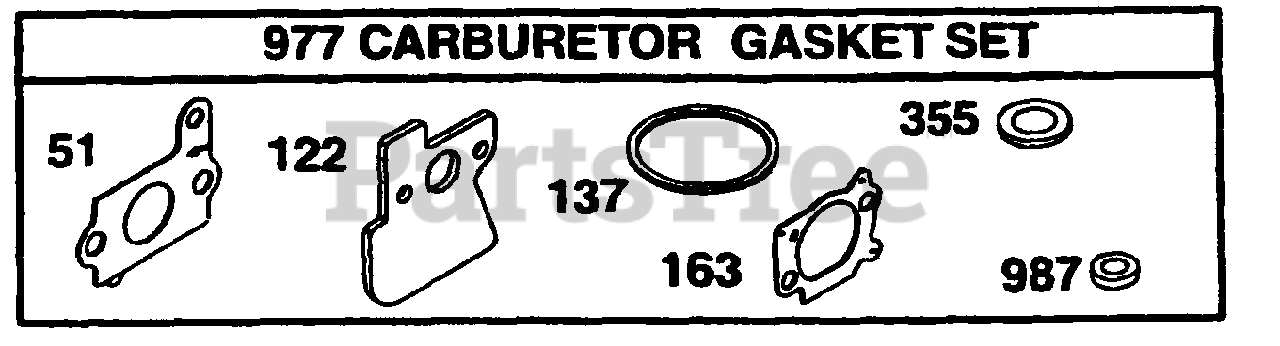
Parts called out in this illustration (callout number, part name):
51	Intake Gasket
122	Intake Gasket
137	Float Bowl Gasket
163	Air Cleaner Gasket
355	Seal Washer
977	Gasket Set Carburetor
987	Throttle Shaft Seal
